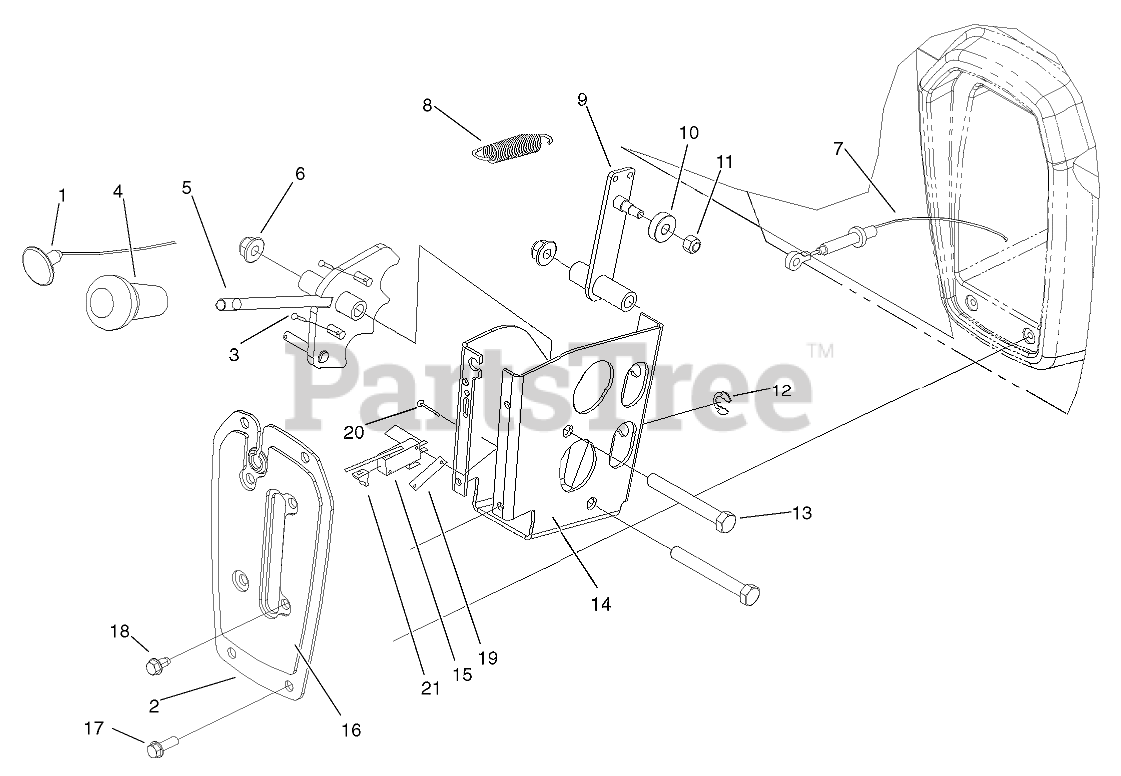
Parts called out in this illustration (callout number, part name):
1	CABLE-CHOKE
2	PLATE-SHIFTER
3	PIN-COTTER
4	KNOB-GRIP, SOFT
5	LEVER-SHIFTER
6	NUT-HF, NI
7	Cable-Shift
8	SPRING-RETURN, PEDAL
9	DETENT
10	BEARING-BALL
11	NUT-LOCK, NI
13	SCREW-HH
14	BRACKET-SHIFT
15	SWITCH-MICRO
16	DECAL-SHIFTER
17	SCREW-HWH
18	SCREW
19	NUT-SPEED
20	SCREW-SPH
21	PLUNGER-SEAL
